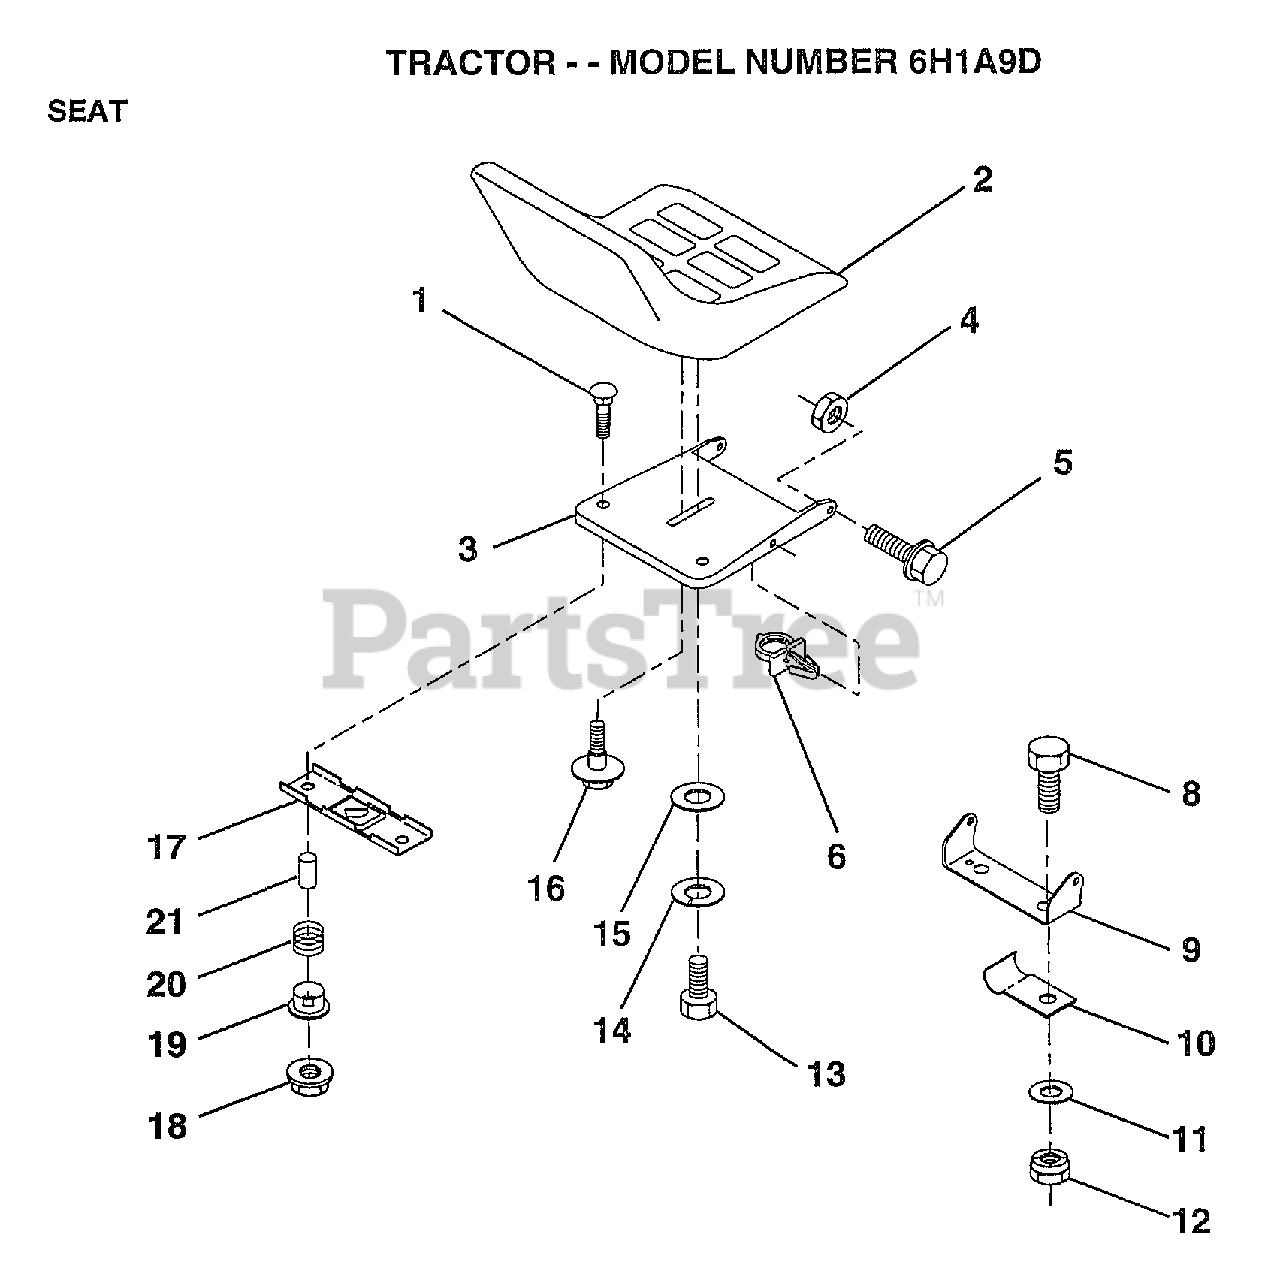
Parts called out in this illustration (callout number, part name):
4	NUT
5	BOLT.SHLD.5/16-18
6	CLIP.PUSH-IN.HING
8	BOLT
9	BRACKET PVT SEAT
10	"CLIP,INSULATOR"
11	WASHER
12	NUT
13	BOLT
14	LOCKWASHER
15	WASHER
16	"BOLT,SHOULDER"
17	BRKT SWITCH
19	BUSHING
20	SPRING
21	SPLIT SPACER
